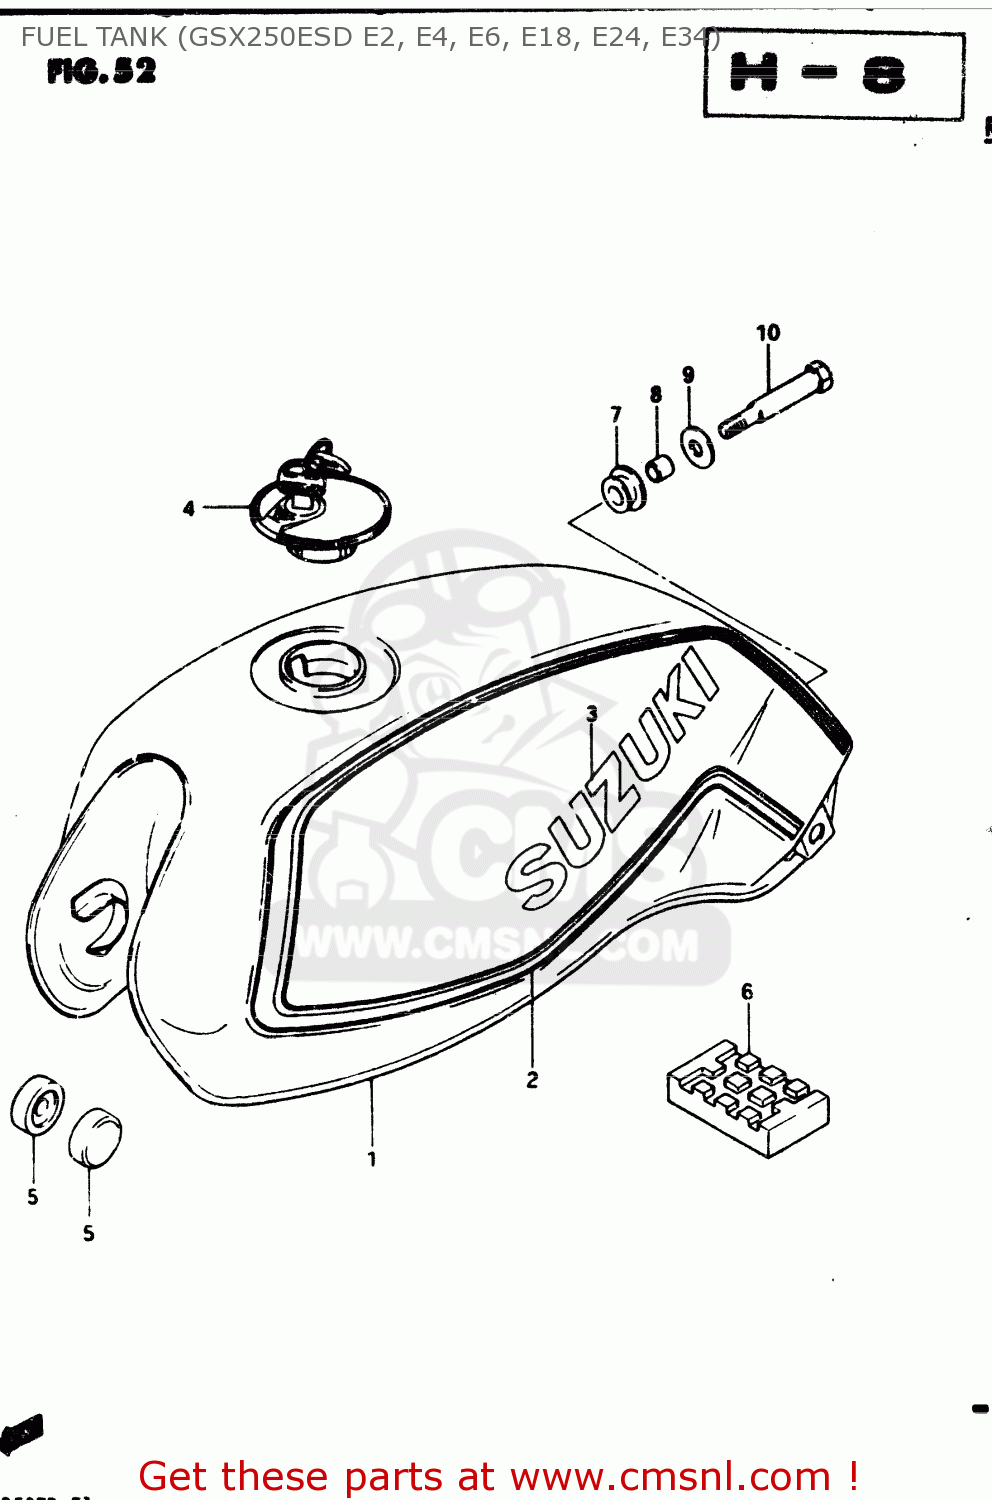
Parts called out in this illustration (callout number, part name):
1	TANK SET, FUEL
2	TAPE SET, FUEL TANK
3	EMBLEM(WHITE)
4	CAP SET,FUEL TANK
5	CUSHION
6	CUSHION,FUEL TANK CTR
7	CUSHION
8	SPACER (6.8X10X10)
9	WASHER (6.5X29X1.6)
10	BOLT(6X60)
